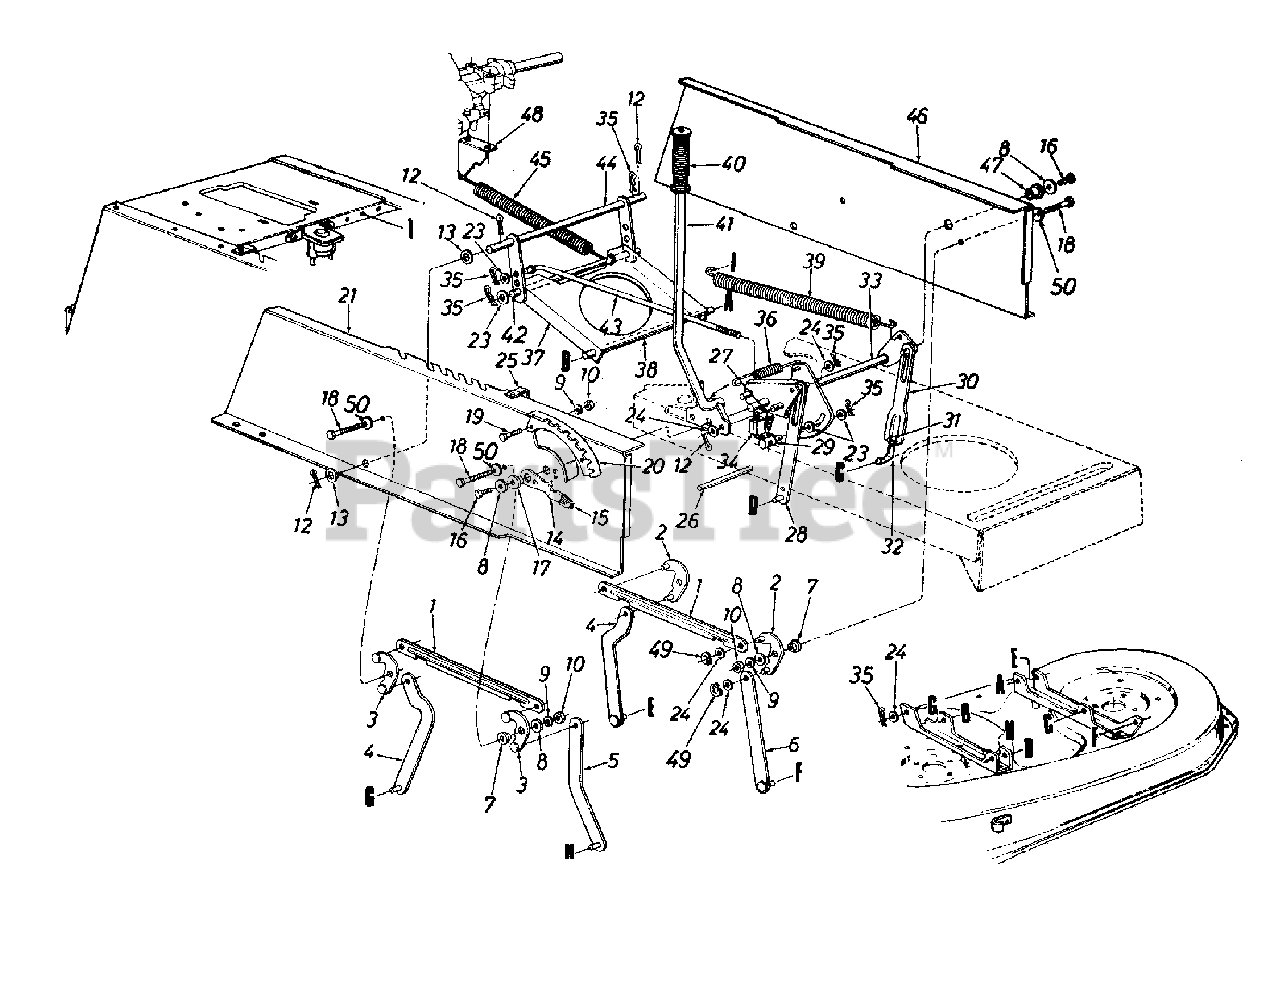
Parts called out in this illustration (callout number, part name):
3	Pivot Link Ass'y.-R.H.
7	Shld. Spacer .318" I.D.
8	Fl-Wash. .344" I.D. x .62" O.D.
9	L-Wash. 5/16" I.D.
10	Hex Nut 5/16-18 Thd. (Gr. 5)
12	Cotter Pin 1/8" Dia.
13	Fl-Wash. .635" I.D. x 1.0" O.D.
14	Height Adj. Stop Lever Ass'y.
15	Knob
16	Hex Wash. TT-Tap Scr.5/16-18 x .75" Lg.
17	Flange Brg. .63" I.D.
18	Hex Wash. Hd. Scr. 5/16-18x .875" Lg.
19	Hex Bolt 5/16-18 x .75" Lg.
20	Index Brkt.
24	Fl-Wash. .531" I.D. x .93" O.D.
25	Clamp
26	Running Board Rod
27	Hex Wash. Hd. Tap Scr.
31	Hex Nut 1/2-20 Thd. (Gr. 5)
32	Lift Link Adjuster
35	Inter. Cotter Pin 3/8" Dia.
36	Extension Spring
39	Extension Spring
40	Grip (Lift Handle)
43	Disengagement Rod
49	"E"-Ring
50	Bell-Wash. .325" I.D.
